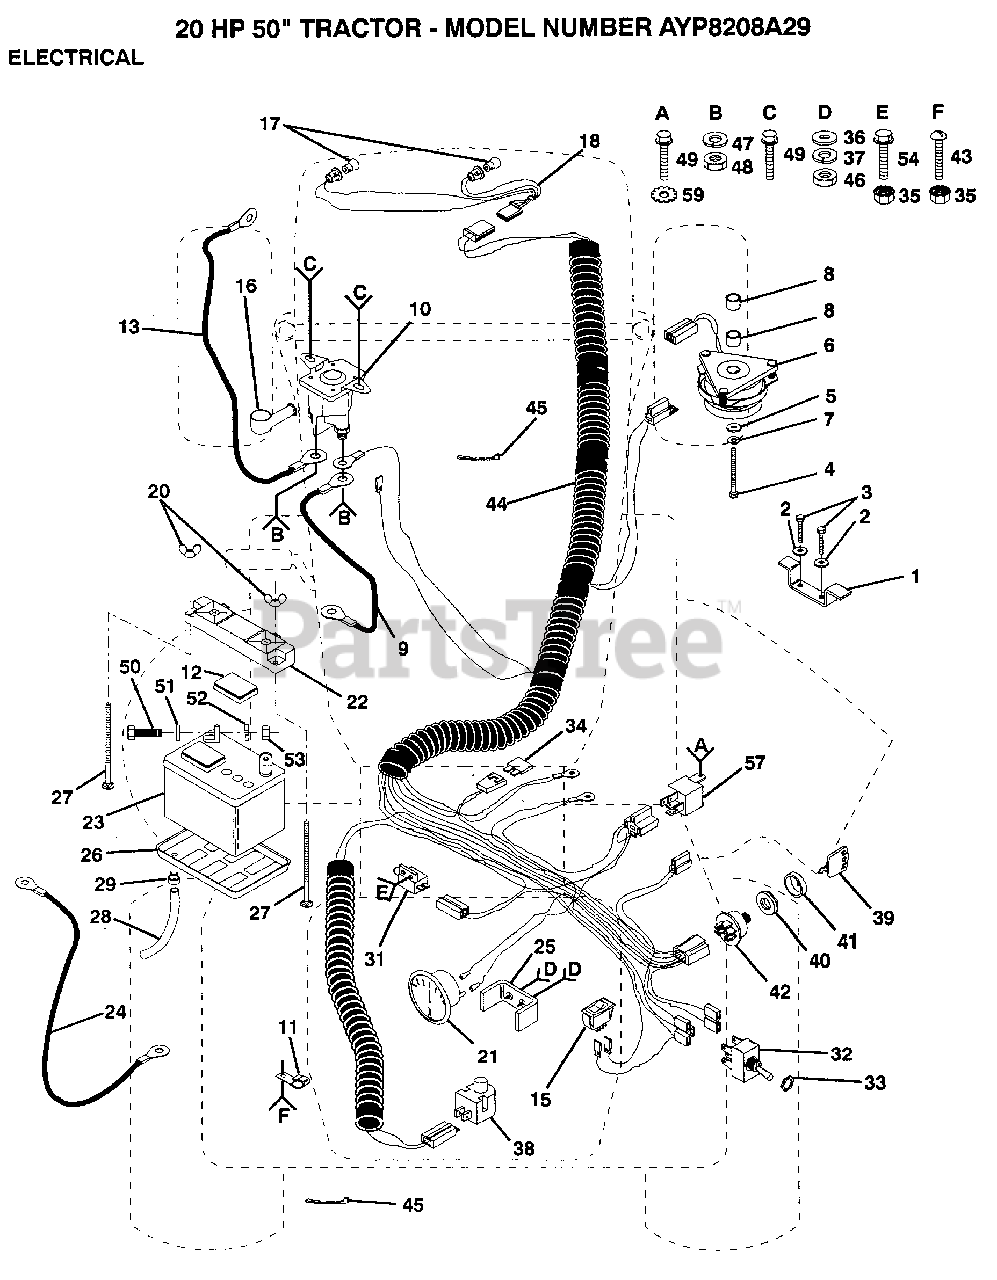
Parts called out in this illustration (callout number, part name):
2	LOCKWASHER
3	BOLT
5	WASHER
7	LOCKWASHER
8	SPACER-CLUTCH
9	CABLE-BATTERY T
12	"CAP,BATTERY "
13	"CABLE,STARTER T"
15	SWITCH LT
21	AMMETER T
24	CABLE T
26	"TRAY T, BATTERY"
27	BOLT
29	HOSE CLAMP T
31	SWITCH-INTER. GT
33	HEX NUT T
34	FUSE HYT
35	"NUT,KEPS"
36	WASHER
38	SWITCH SEAT
39	KEY
40	NUT IGNITION
44	HARNESS
45	WIRE TIE
48	NUT
49	SCREW ST
50	BOLT LT
51	WASHER
52	LOCKWASHER
54	SCREW
57	RELAY ASSY T
59	LOCKWASHER
